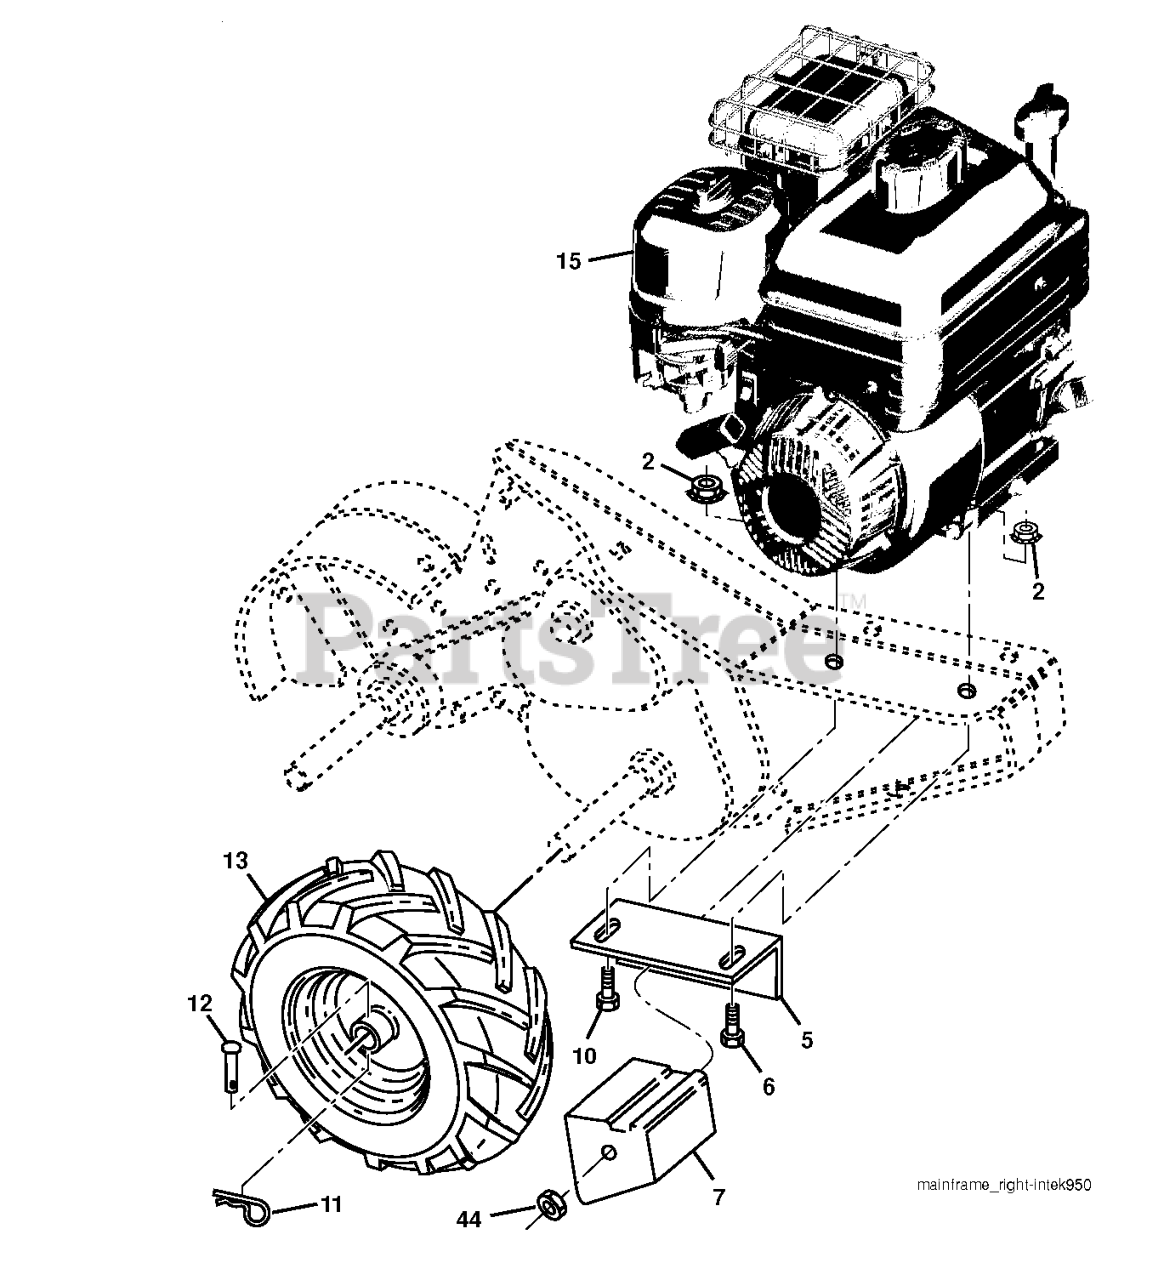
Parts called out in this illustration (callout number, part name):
2	LOCKNUT-FLANGE 5/16-18
5	BRACKET.REINFORCEMENT.RH.BLACK
6	BOLT, HEX 5/16-18X1-3/4
7	COUNTERWEIGHT.RH
10	BOLT
11	RETAINER M
12	RIVET
13	WHEEL 16X4X8.DR TILLER RH.417
